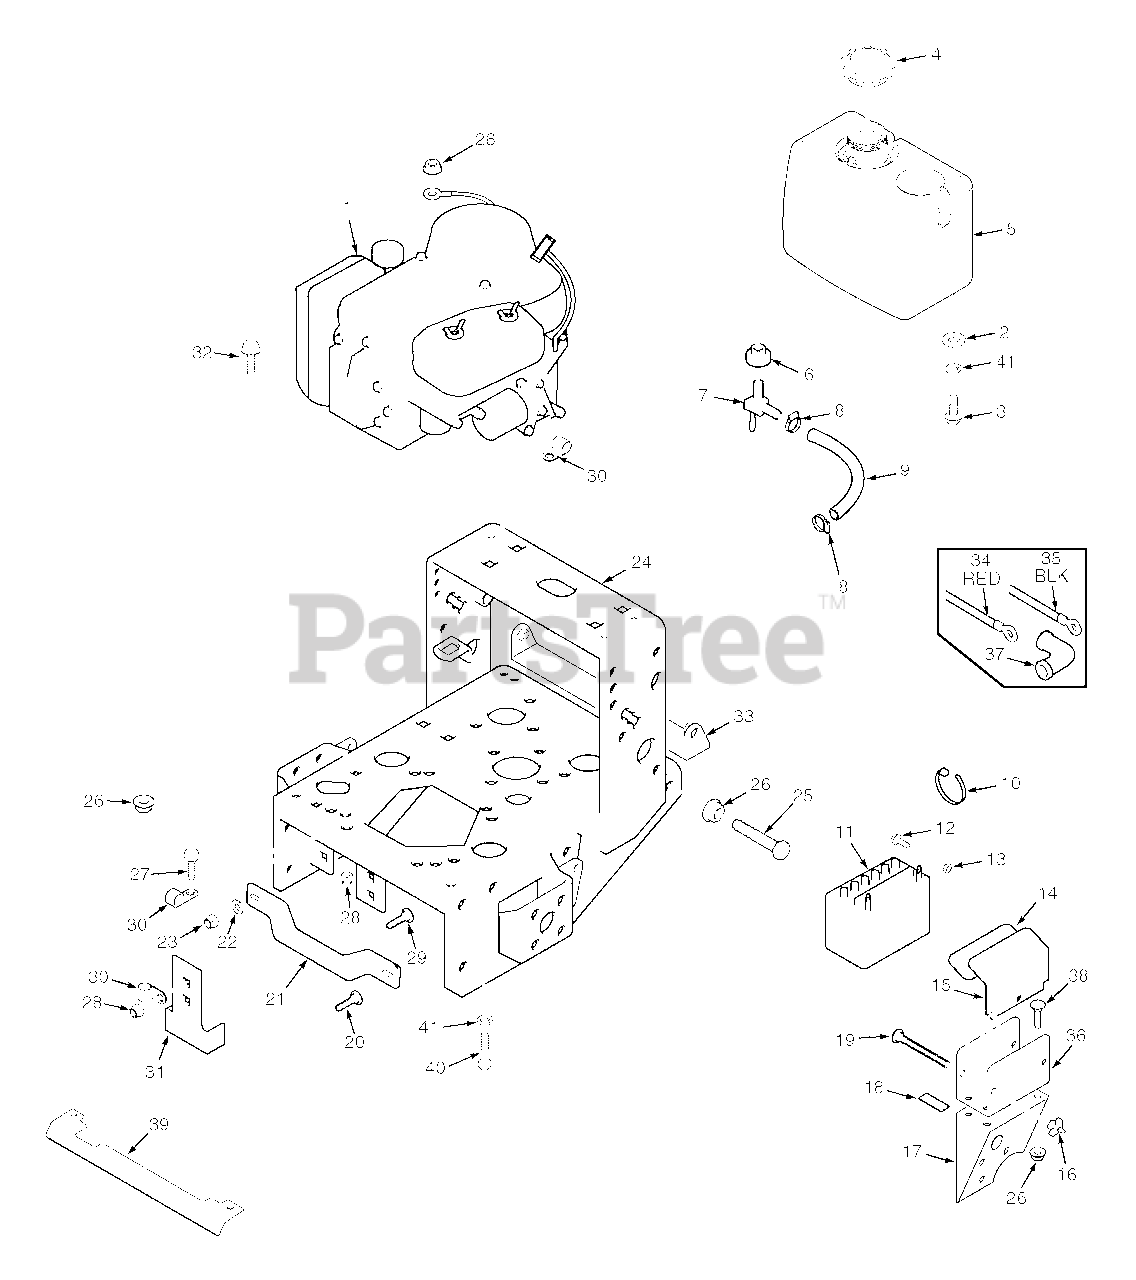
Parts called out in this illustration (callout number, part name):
1	Engine, 21KAE Kawasaki
2	Flatwasher, 5/16 (.375 x 875 x .083)
3	Capscrew, 5/16-18 x 1" Hex Head
4	Cap, Fuel Tank
5	Fuel Tank Assy.
6	Bushing
7	Valve, Fuel Shut-off
8	Clamp, Fuel Hose
9	Fuel Hose, 1/4 ID x 20"
10	Cable Tie
11	Battery
12	Bolt, 1/4-20 x .50"
13	Nut, 1/4-20
15	Battery Cover
16	Wing Nut, 1/4-20
17	Battery Support
18	Pad, Rubber
19	Bolt, 1/4-20 x 6" Carriage
20	Carriage Bolt, 3/8-16 X 1-1/4"
21	Brace, (20" Large Frame)
22	Flat Washer .391 x .938 x .105
23	Nut, 3/8-16 Elastic Stop
24	Engine Deck, 20" Wide, w/decals
25	Bolt, 5/16-18 x 2" Hex Head
26	Nut, 5/16-18 Serr. Flange
27	Hex Head Bolt, 5/16-18 x .75"
28	Nut, 5/16-18 Elastic Stop
29	Carriage Bolt, 5/16-18 x 1"
31	Clutch Bracket
32	Cap Scrw, 5/16-18 x 1.50" Sr. Flg.
33	Pulley Guard, 20" Frame
34	Battery Cable, 31.5" Red
35	Battery Cable, 31.5" Black
36	Battery Box
37	Rubber Boot
38	Carriage Bolt, 5/16-18 x .75"
39	Heatshield (20" Large Frame)
40	Bolt, 5/16-18 x 1" Sr. Flg. Hex Head
41	Lock Washer 5/16"
